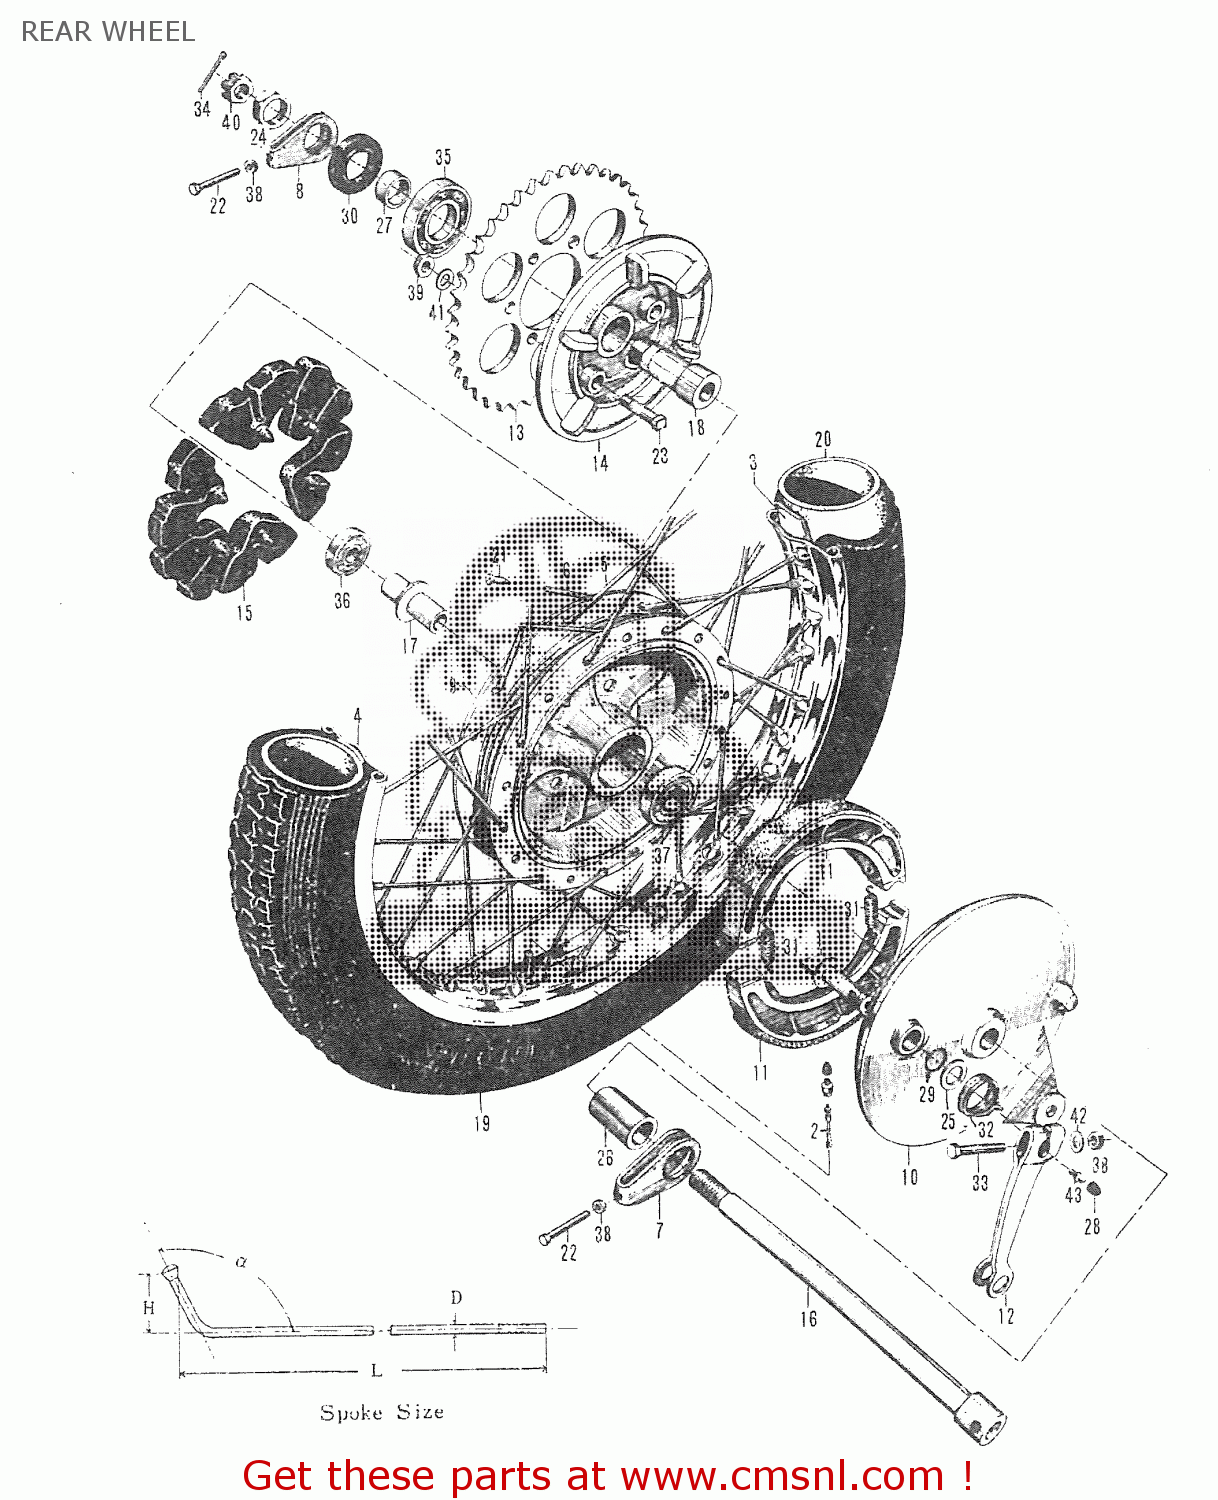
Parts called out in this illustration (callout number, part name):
1	CAM,FRONT BRAKE
2	VALVE,INNER TUBE
3	PROTECTOR,INNER TUBE
4	RIM,FRONT WHEEL
5	SPOKE,WHEEL
6	SPOKE,WHEEL
7	ADJUSTER,CHAIN
8	ADJUSTER,CHAIN
9	DRUM,REAR HUB
10	PANEL,REAR HUB
11	SHOE SET,BRAKE (MCA)
12	LEVER,REAR BRAKE CAM
13	SPROCKET,REAR
14	DRUM,REAR SPROCKET MOUNT
15	CUSHION,REAR DRUM
16	AXLE,REAR
17	SPACER
18	SHAFT,SPROCKET MOUNTING
19	TIRE
20	TUBE ASSEMBLY,WHEEL,INNER
21	NIPPLE,SPOKE
22	BOLT
23	BOLT
24	NUT
25	WASHER (15X24X1.6)
26	REAR AXLE SPACER
27	SPROCKET MOUNTING DRUM SHAFT SPACER
28	GREASE NIPPLE CAP
29	O-RING,BOSS
30	OIL SEAL
31	SPRING
32	SPRING
33	HEXAGON NUT
34	COTTER PIN
35	BEARING
36	BEARING
37	BALL BEARING
38	HEXAGON NUT
39	SMALL HEXAGON NUT
40	CASTLE NUT
41	LOCK WASHER
42	FLAT WASHER
43	GREASE NIPPLE
